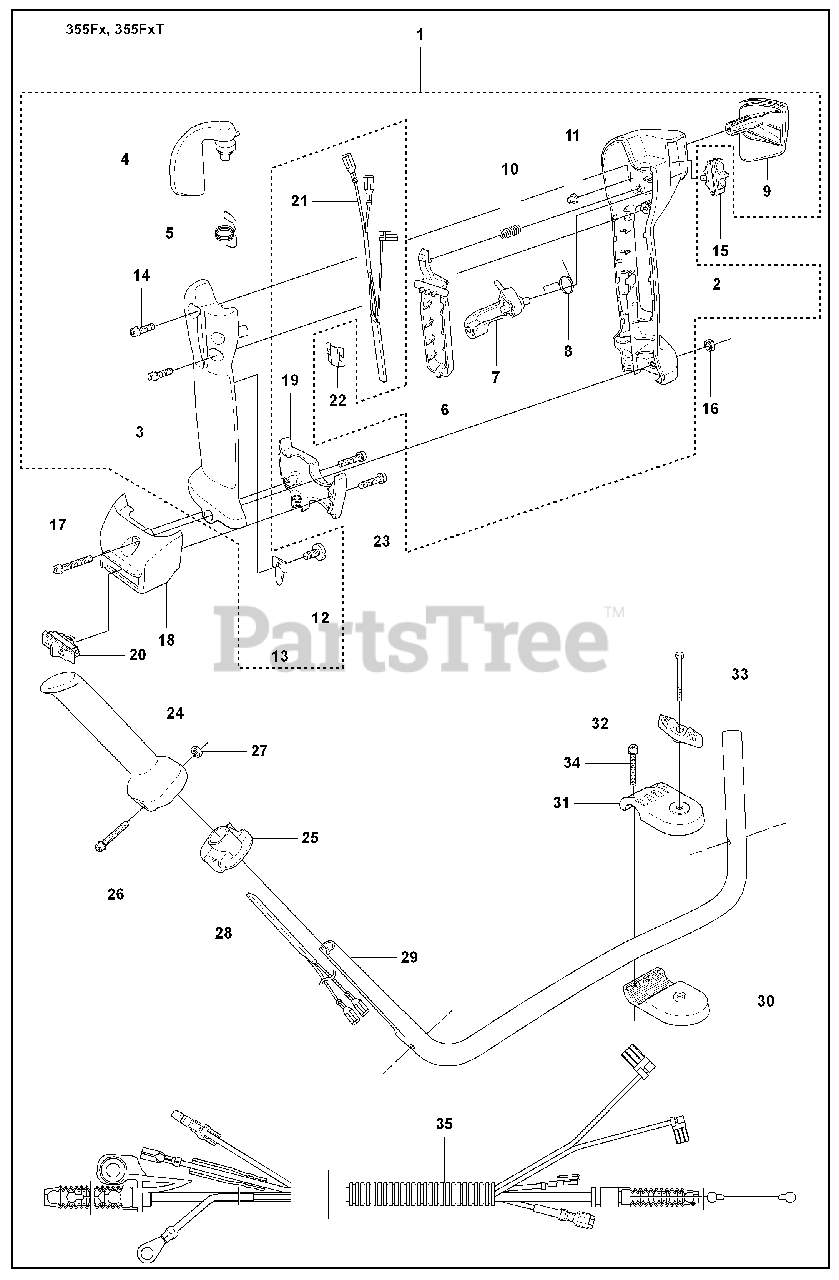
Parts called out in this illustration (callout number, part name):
1	THROTTLE HANDLE
2	HANDLE
3	HANDLE
4	THROTTLE TRIGGER
5	RP SPRING
6	THROTTLE LOCK
15	STOP BUTTON
16	NUT M6M M5
17	SCREW
18	HOLDER
19	HOLDER
20	SWITCH (G)
21	HEATING ELEMENT
23	SCREW
27	NUT M6M M5
28	HEATING ELEMENT
29	%HANDLE
30	HANDLE HOLDER LOWER
31	HANDLE HOLDER UPPER
33	%SCREW
35	WIRING
